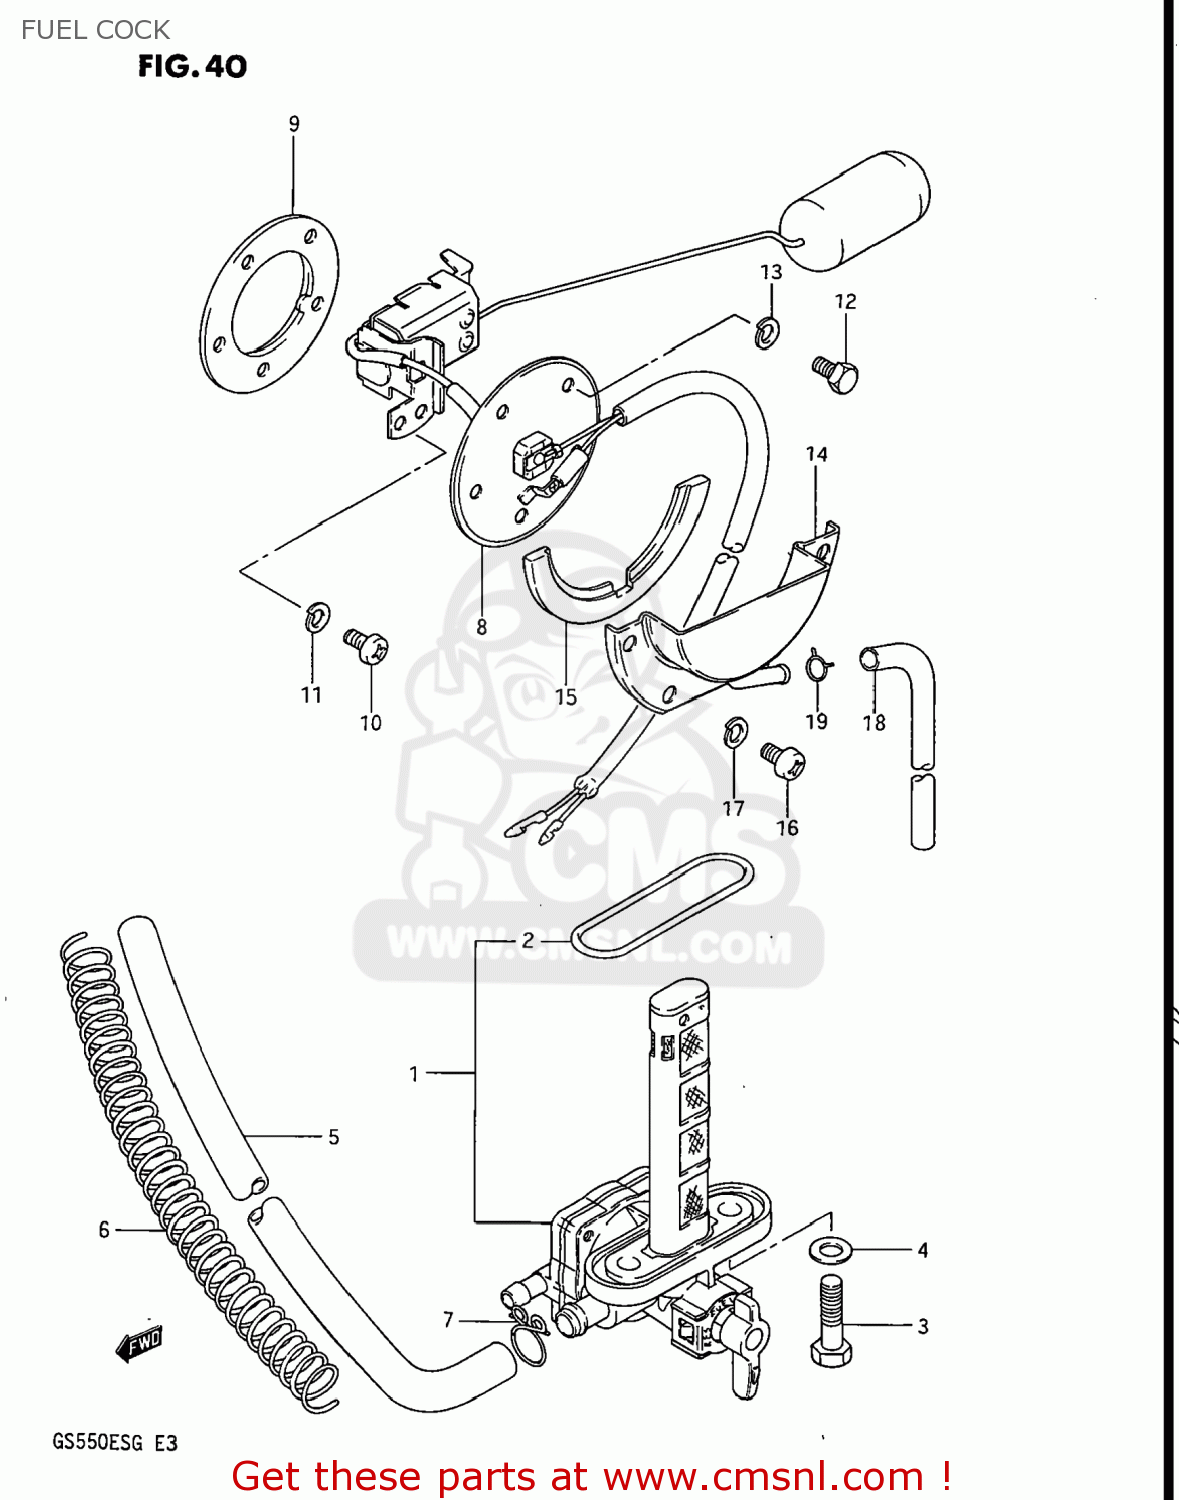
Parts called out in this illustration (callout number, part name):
1	COCK ASSY,FUEL
2	O RING
3	BOLT(6X20)
4	GASKET
5	HOSE
6	SPRING
7	CLIP
8	GAUGE ASSEMBLY,FUEL LEVEL
9	GASKET,FUEL LEVEL GAUGE (NAS)
10	SCREW 5X10
11	LOCK WASHER
12	BOLT
13	LOCK WASHER
14	PLATE,FUEL DRAIN
15	GASKET (NAS)
16	SCREW
17	LOCK WASHER
18	HOSE,FUEL
19	CLIP
